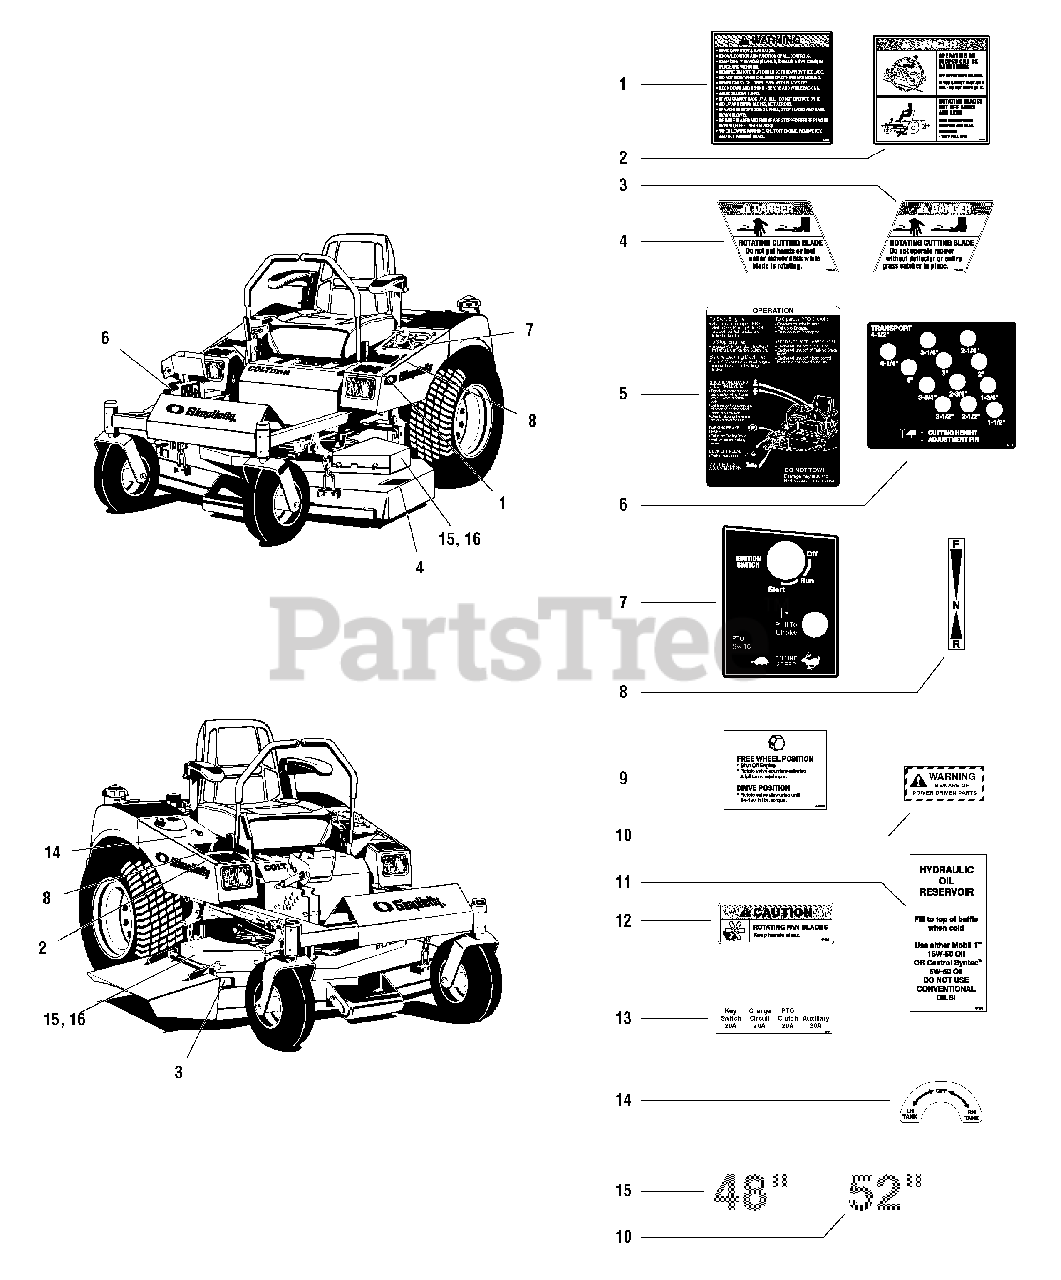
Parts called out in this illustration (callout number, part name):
1	DECAL, Warning
2	DECAL, Danger
3	DECAL, Danger (Chute In Place)
4	DECAL, Danger (Hand Under Deck)
5	DECAL, Operation
6	DECAL, Lift Plate
7	DECAL, Instrument Panel
8	DECAL, Direction
9	DECAL, Hydro Release Valve
10	DECAL, Warning (on top of mower deck)
11	DECAL, Oil Reservoir
12	DECAL, Caution Fan
13	DECAL, Fuse Location
14	DECAL, Fuel Valve
